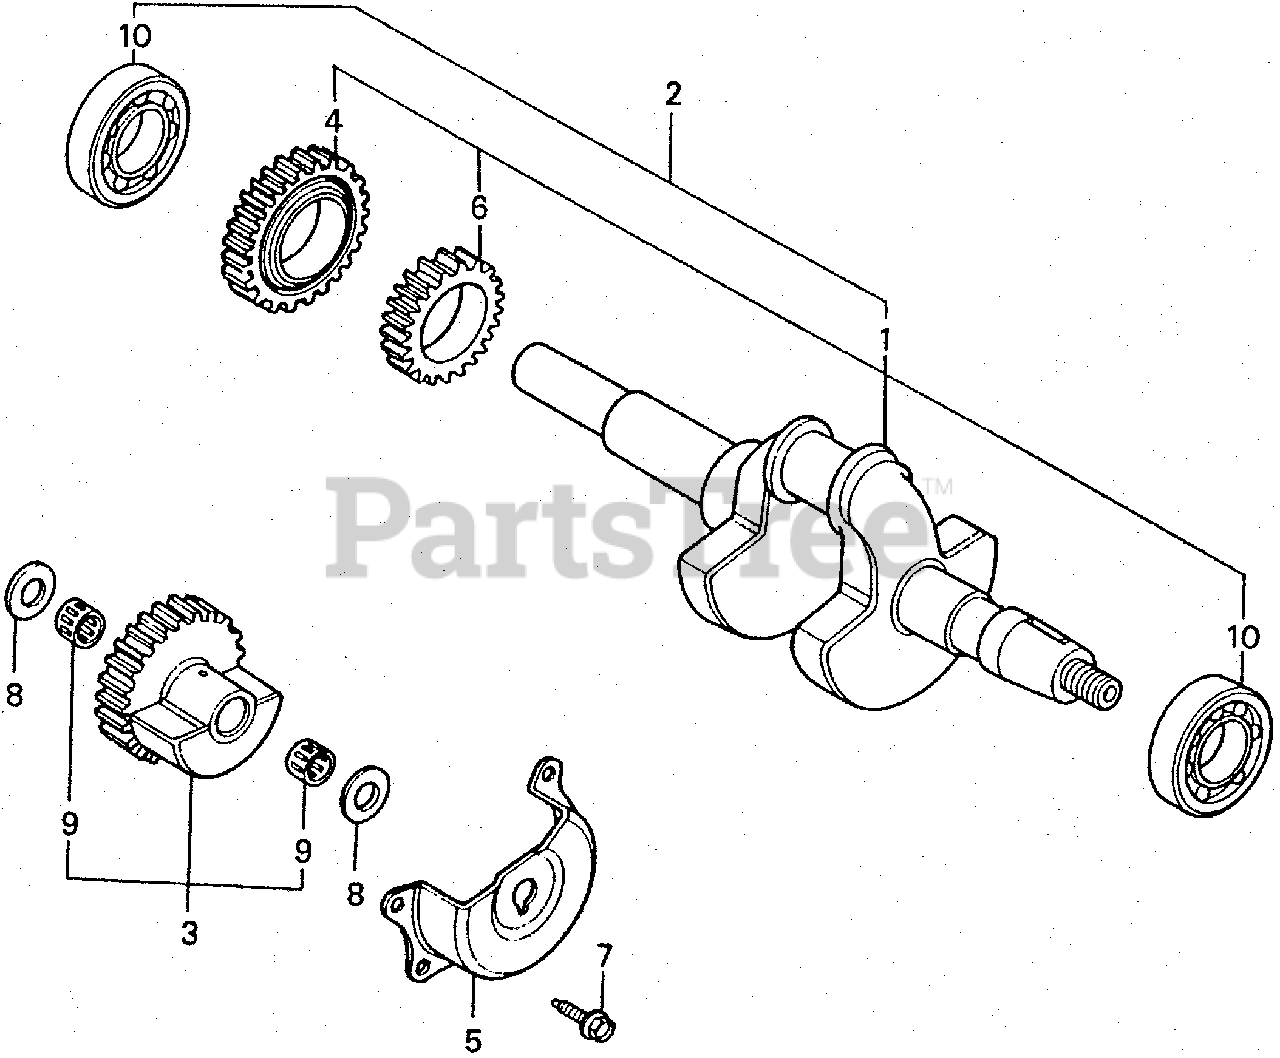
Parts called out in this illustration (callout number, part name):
1	CRANKSHAFT (S-TYPE)
2	CRANKSHAFT (S-TYPE)
3	WEIGHT, BALANCER
4	GEAR, BALANCER
5	COVER, BALANCER
6	GEAR, TIMING
7	BOLT, FLANGE (6X12) (CT200)
7	BOLT, FLANGE (6X16)
8	WASHER, THRUST (15MM)
9	BEARING, NEEDLE
10	BEARING, RADIAL BALL (6206)
